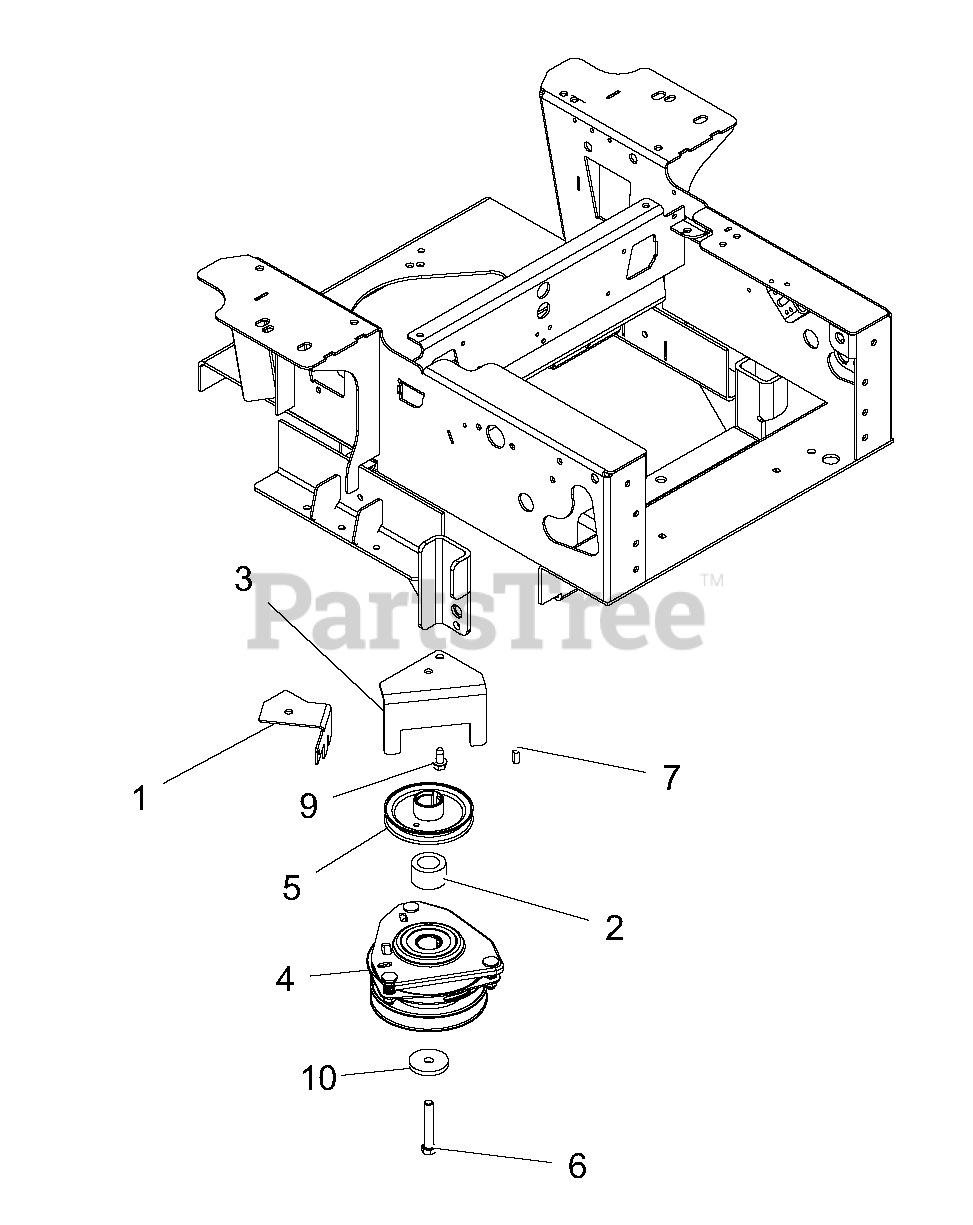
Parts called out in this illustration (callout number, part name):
1	HD CLUTCH WIRE GUARD - BLK
2	SPACER, 1.125 C 1.750 X .712
3	STOP, PRO-TURN CLUTCH-BLACK
4	CLUTCH, OGURA GT1A-EH01
5	PULLEY, 4.50 OD X 1.127 ENGINE
6	BLT-HEX .44-20X2.75 GR5 EP80 YWZC
7	KEY-SQ .250X.250X.625
9	SCR-TAP .38-16X.75 HWH TR YWZ
10	WSHR-FL-STL .469X2.00X.25 YWZC
